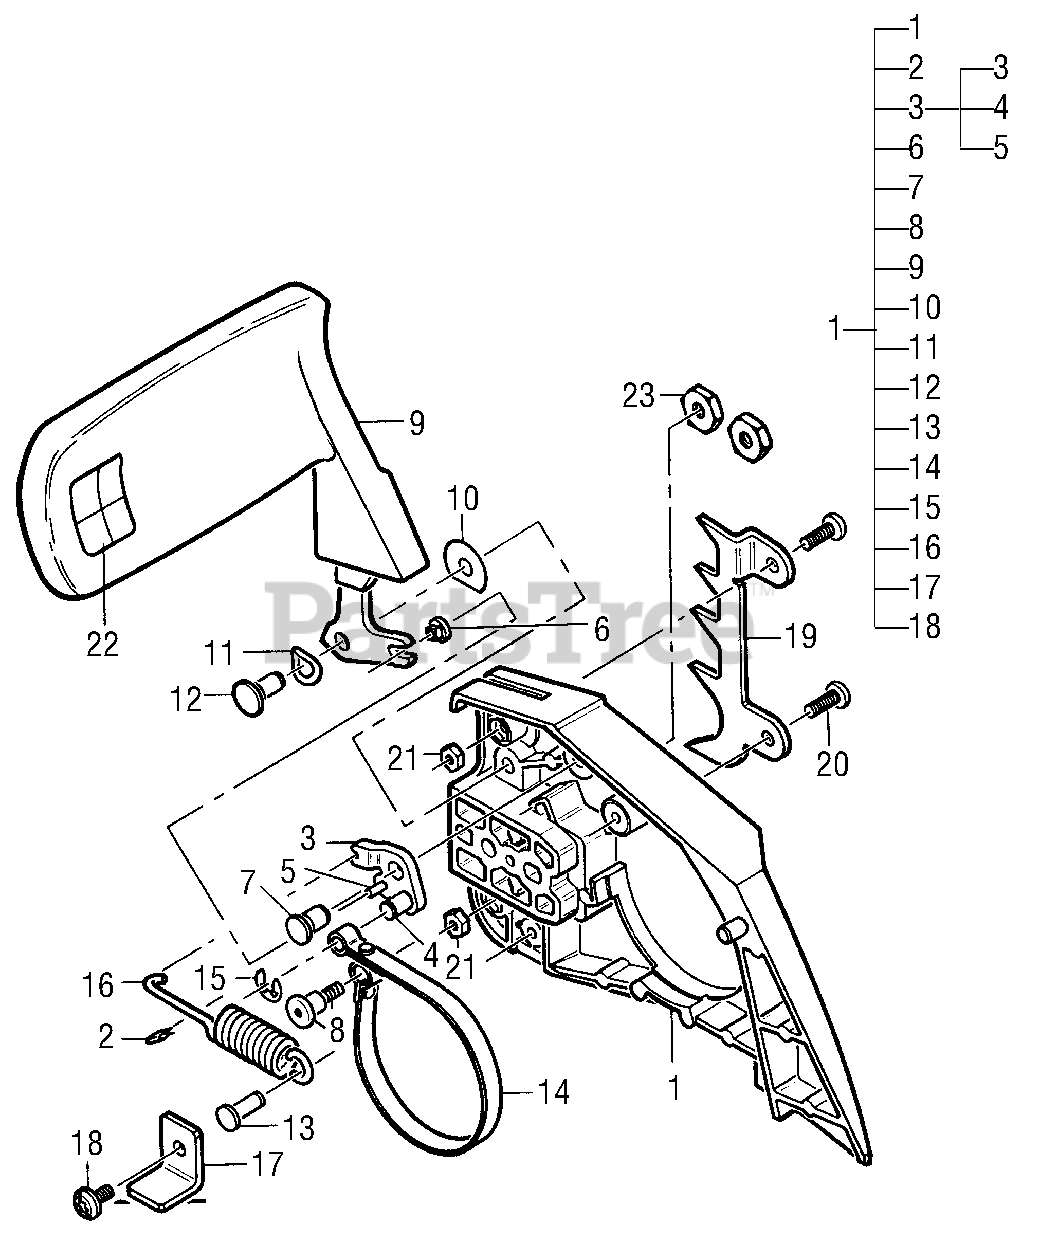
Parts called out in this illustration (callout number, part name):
1	Chain Brake, Inertia (Yellow)
2	Clip, "U"
3	Latch Asy, Chain Brake
4	Pin, Brake Band
5	Pin, Latch
6	Slider
7	Pivot, Latch
8	Screw, Band Anchor
9	Flat, Brake
10	Washer, "D"
11	Washer, Spring
12	Lever Pivot
13	Pin, Spring Hook
14	Band, Brake
15	Ring, Retaining
16	Spring, Chain Brake
17	Stop, Chain
18	Screw, 10-24x.62 Tr Hd Torx
19	Spike
20	Screw
21	Nut, 10-24
22	Label, Safety
23	Nut, Bar 5/16-18
